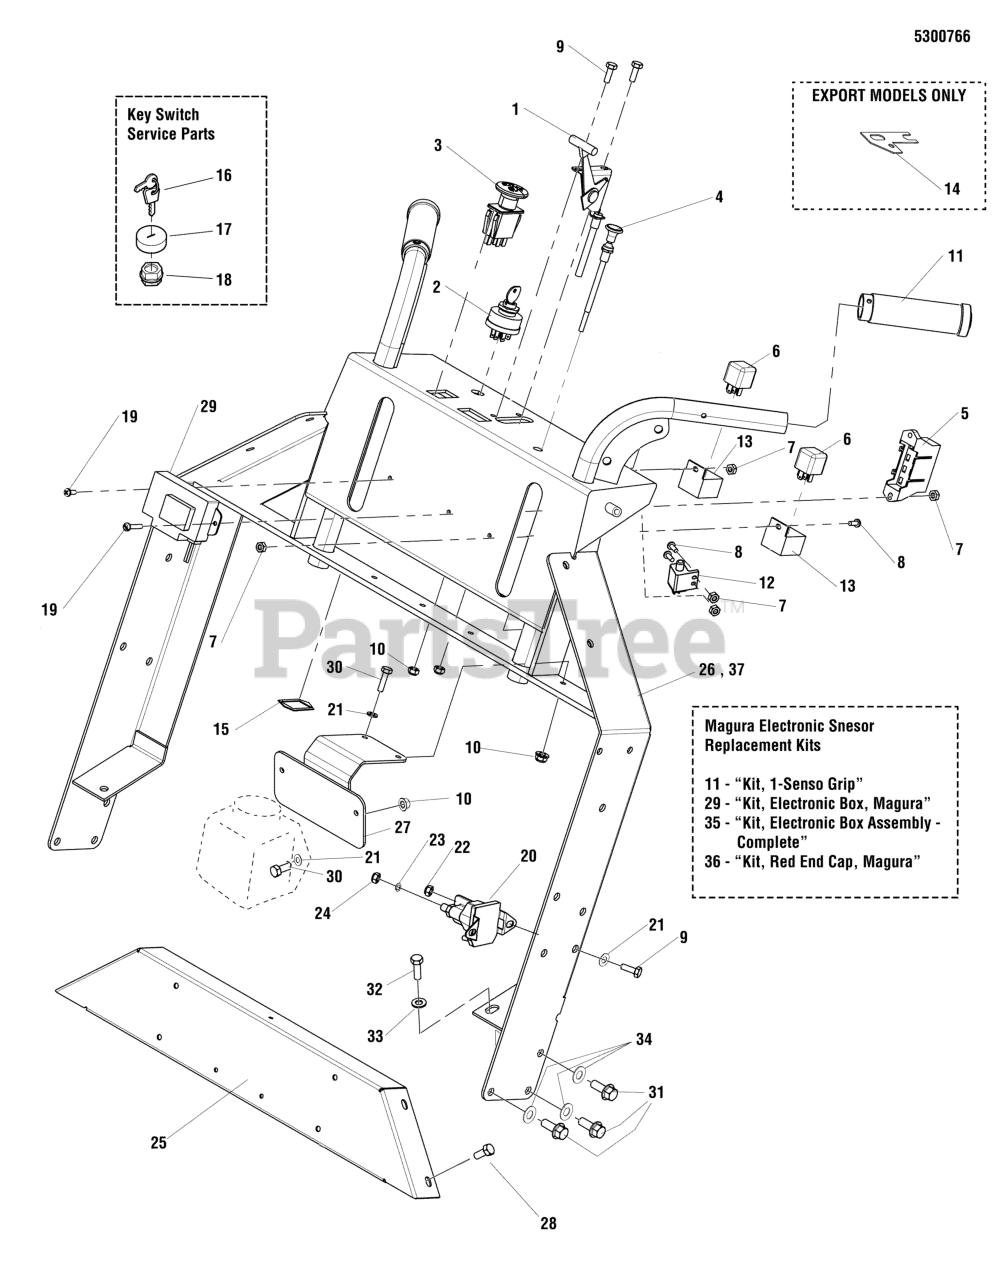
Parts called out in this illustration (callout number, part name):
1	CABLE THROTTLE, 48"
2	SWITCH, IGNITION, 6 POST
3	SWITCH, BLADE ENGAGEMENT
4	CABLE, CHOKE CONTROL, 51"
5	FUSE, BLOCK (SV)
6	RELAY, 12V, 40A
7	NUT, HEX, #10-24
8	SCREW, #10-24 X 1/2" ROUND PHILLIPS
9	BOLT, 1/4-20 X 3/4" GD5
10	NUT, 1/4-20 HEX NYLON FLANGE
12	SWITCH, PLUNGER, N.O.
13	SOCKET, RELAY
14	PLATE, THROTTLE STOP
15	SWITCH RETAINER RING
16	KEY, IGNITION MOLDED SET
17	COVER, PLASTIC, SNAP ON
18	PLASTIC NUT
19	SCREW, #10-24 X 3/4" ROUND PHILLIPS
20	SOLENOID
21	WASHER, 1/4 SAE
22	NUT, 1/4-20 HEX SERR. FLANGE
23	WASHER, 5/16 LIGHT LOCK
24	NUT, Hex Jam, 5/16-24
25	HANDLE BAR COVER W/ DECALS, CCW
26	HANDLE BAR W/ DECALS, CCW
27	WELD, HYDRAULIC RESERVOIR
28	BOLT, 5/16-18 X 3/4 SELF TAP
29	KIT, ELECTRONIC BOX, MAGURA (SV)
30	BOLT, 1/4-20 X 1" GD5 CZ
31	BOLT, 3/8-16 X 1" GD5 CZ
32	BOLT, 5/16-18 X 1" GD5
33	WASHER, 5/16" USS
34	WASHER, 3/8 SAE
35	KIT, ELECTRONIC GRIP ASSEMBLY, COMPLETE (SV)
36	KIT, ROD END CAP, MAGURA (SV)
37	WELD, DDS HANDLE BAR - RED
